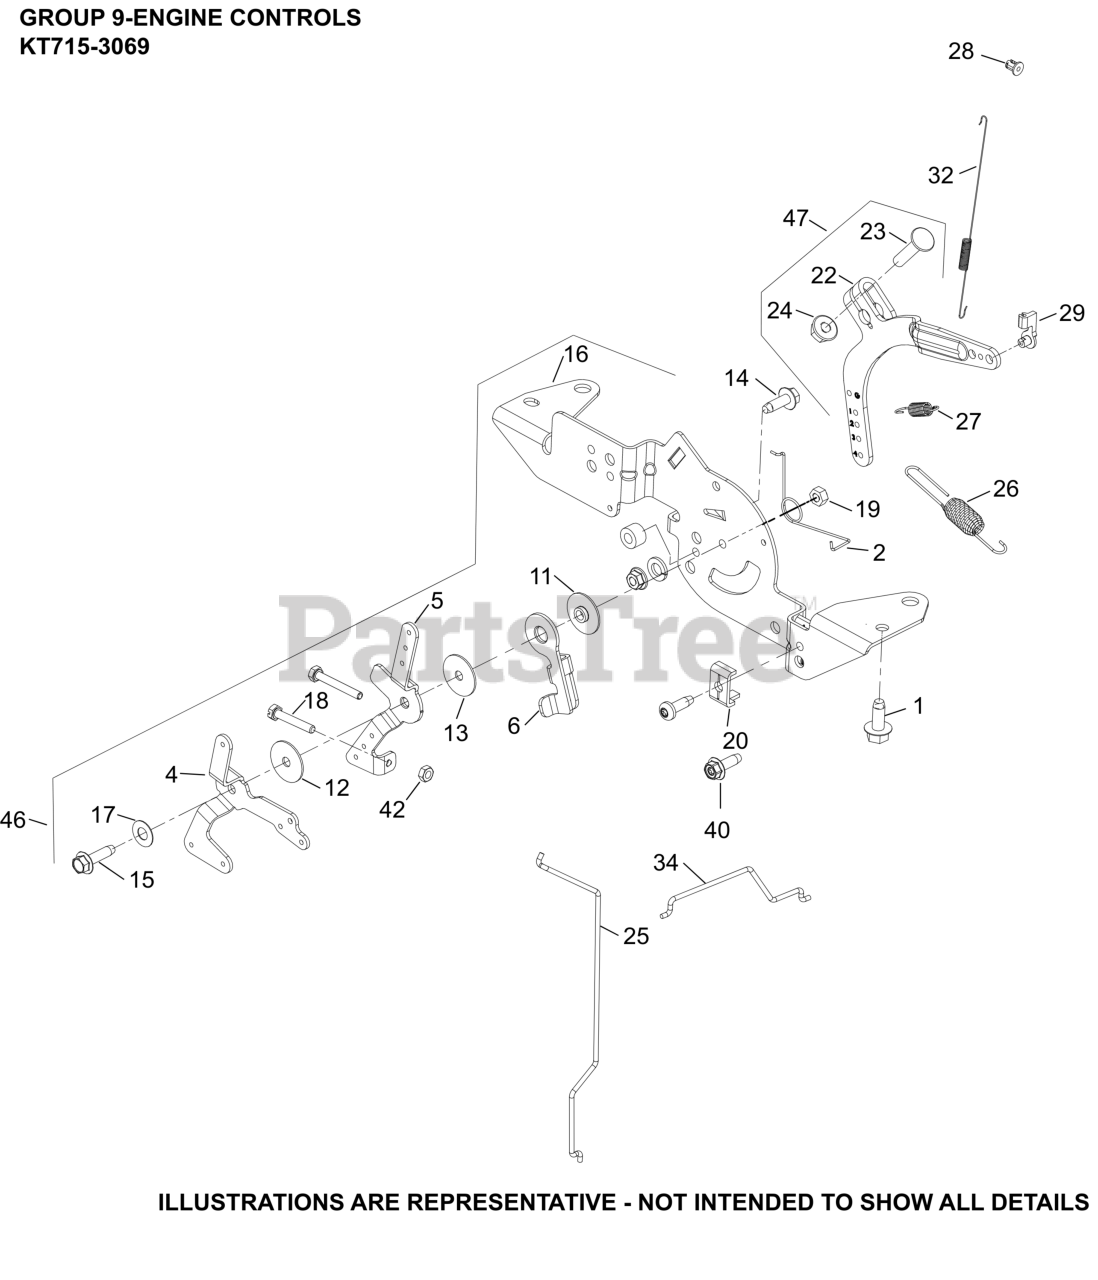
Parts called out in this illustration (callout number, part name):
1	SCREW, THREAD FORMING
2	SPRING, CHOKE RETURN
4	LEVER, CHOKE
5	LEVER, THROTTLE CONTROL
6	LEVER, THROTTLE ACTUATOR
11	SPACER, CONTROL ASSEMBLY
12	WASHER, FLAT 5.5 MM
13	WASHER, FLAT 5 MM
14	SCREW, THREAD FORMING
15	SCREW, THD FRM-USE 25 086 473-S
16	BRACKET, SPEED CONTROL
17	WASHER, SPRING 1/4"
18	SCREW, SLT HD CAP M4X0.7X25
19	NUT, LOCK M5X.8
20	CLAMP, CABLE CABLE
22	LEVER, GOVERNOR - (#2409069S)
23	BOLT, RD HD SQ NECK M6X1.0X25
24	NUT, FLG M6X1.0
25	LINKAGE, CHOKE
26	SPRING, GOVERNOR (PURPLE)
27	SPRING, GOVERNED IDLE
28	BUSHING, LINKAGE RETAINING
29	BUSHING, THROTTLE LINKAGE
32	SPRING, LINKAGE
34	LINKAGE, THROTTLE
40	SCREW, THREAD FORMING
42	NUT, M4X0.7
46	CONTROL ASSEMBLY, DUAL WIRE
47	LEVER, GOVERNOR ASSEMBLY
